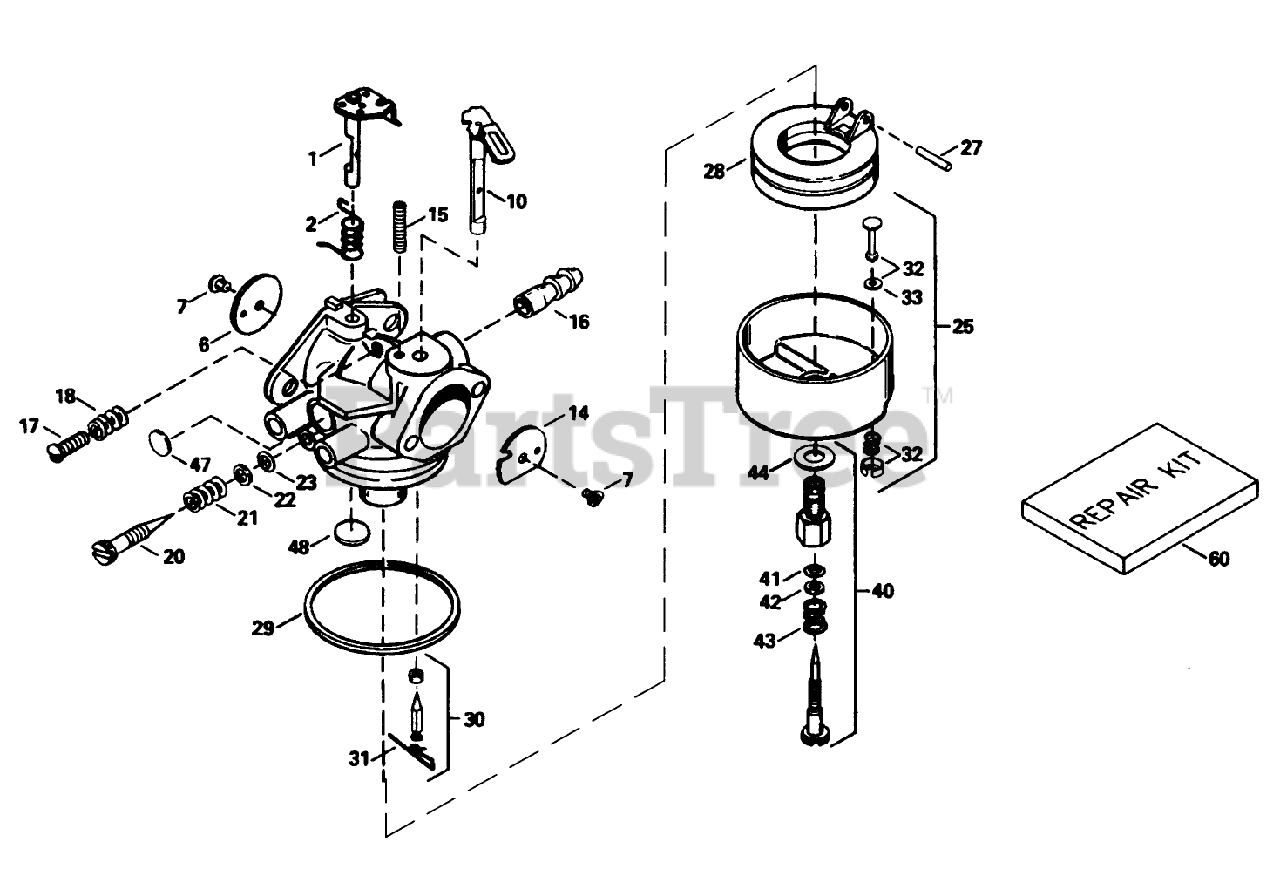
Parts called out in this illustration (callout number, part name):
1	Throttle Shaft and Lever ASM
2	Spring-Return, Throttle
6	Shutter-Throttle
7	Screw-Shutter
10	Choke Shaft and Lever ASM
14	Shutter-Choke
15	Spring-Positioning, Choke
16	Fitting-Fuel
17	Screw-Throttle Crack Screw / Idle Speed
18	Spring-Tension
20	Screw-Idle Mix
21	Spring-Tension
22	Washer
23	ORing
25	Float Bowl Asm. (Incl. Ref. # 32, 33)
27	Shaft-Float
28	Float
29	O Ring-Bowl, Float
30	Inlet Needle, Seat Clip Assy. (Incl. No. 13)
31	Clip-Spring
32	Bowl Drain ASM
33	Gasket-Plunger, Drain
40	Adjustment Screw Assy.,Main (Incl. Ref. #5A,21,23 30)
41	ORing
42	Washer
43	Spring
44	Washer-Bowl Nut
47	Plug-Welch, Idle Mixture Well
48	Plug-Welch, Atmospheric Vent
60	Kit-Repair
